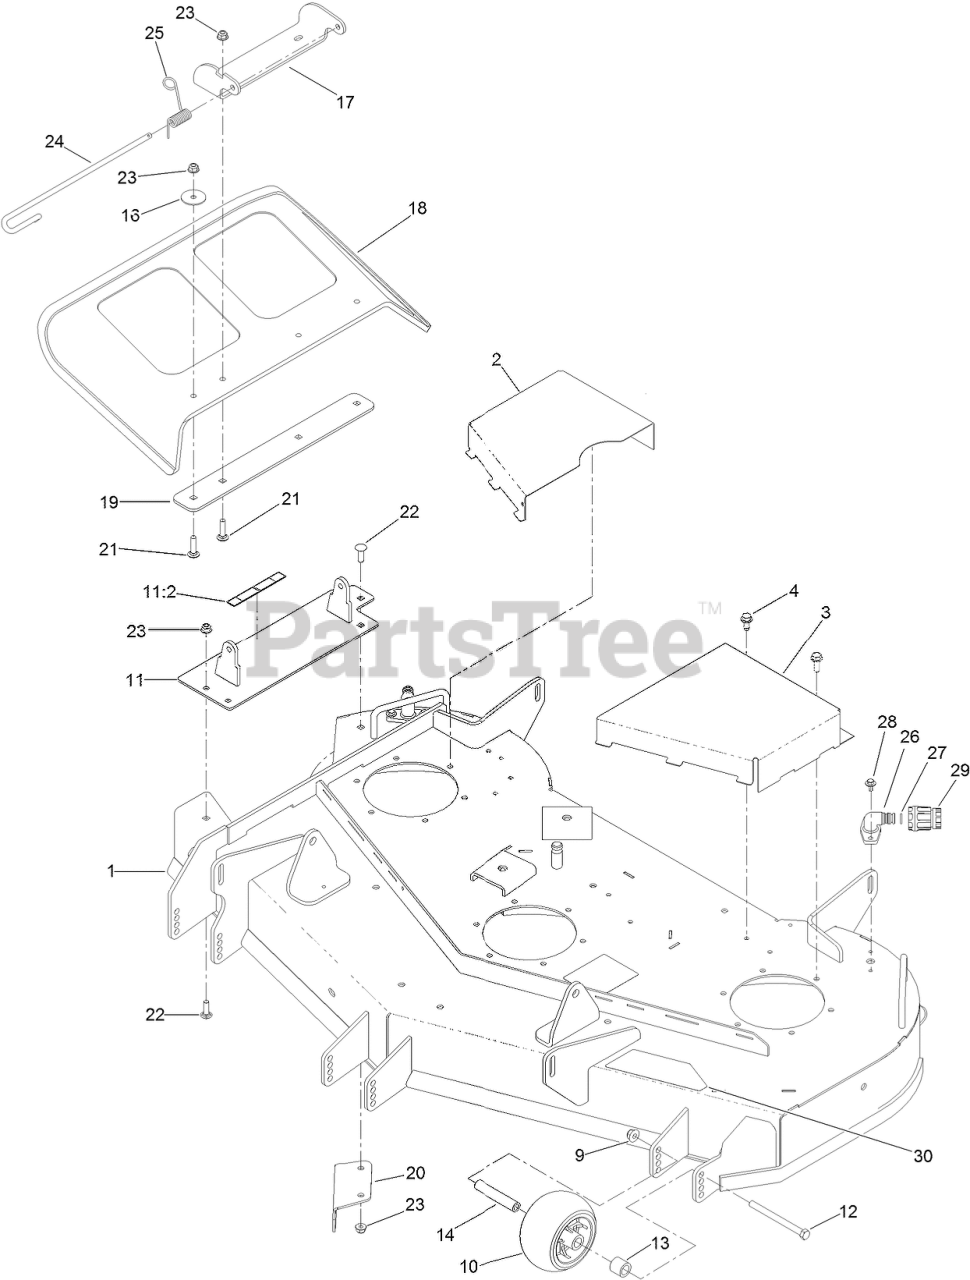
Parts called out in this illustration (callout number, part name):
1	48 INCH DECK ASM
2	COVER-BELT
3	COVER-BELT
4	SCREW-HWHTF
9	NUT-HF, NI
10	ROLLER-SCALP, ANTI
11	PIVOT-DEFLECTOR
11:2	DECAL-DANGER
12	SCREW-HH
13	SPACER-AXLE, REAR
14	TUBE-SPANNER
16	WASHER-FLAT
17	BRACKET-DEFLECTOR, UPPER
18	DEFLECTOR
19	PLATE-DEFLECTOR
20	BAFFLE-CUTOFF
21	SCREW-CARR
22	SCREW-CARR
23	NUT-HF, NI
24	PIN-CHUTE
25	SPRING-TORSION
26	FITTING-WASHOUT
27	O-RING
28	SCREW-HHFTF
29	CONNECTOR-HOSE
30	DECAL-DECK
